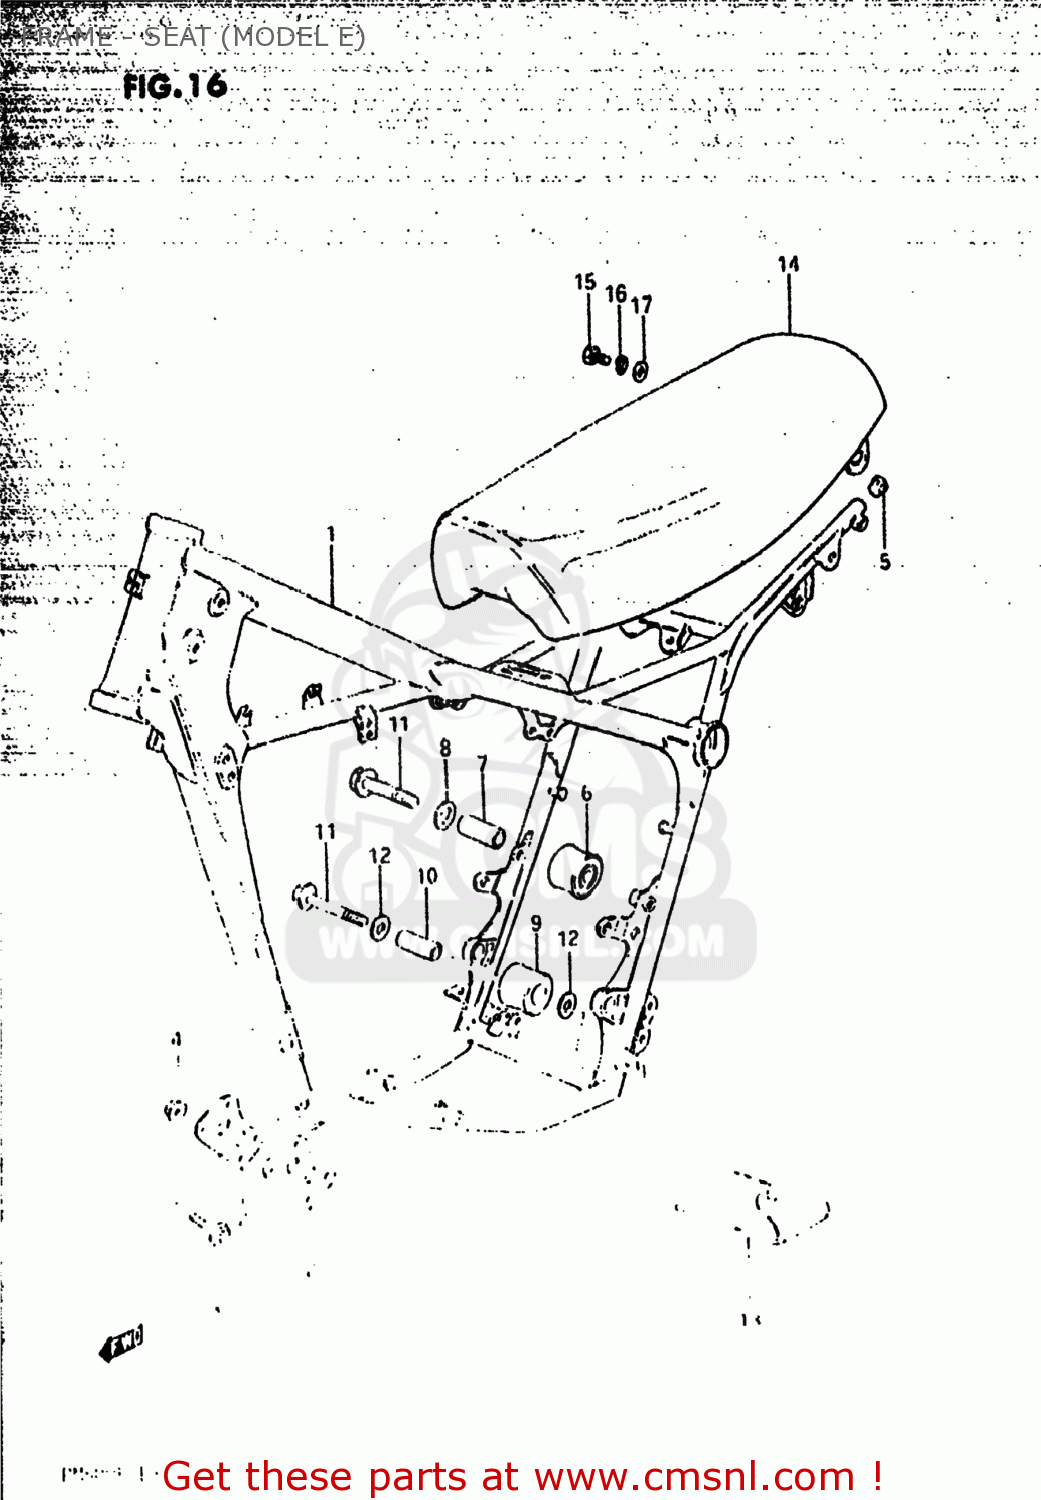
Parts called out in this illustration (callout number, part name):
1	FRAME
2	PLATE,ENGINE MOUNTING
3	BOLT(8X75)
4	NUT
5	PLUG(OD:17)
6	ROLLER,CHAIN
7	SPACER,CHAIN LENGTH ROLLER
8	WASHER
9	ROLLER,CHAIN LENGTH CONTROL
10	SPACER(8.6X12X25.5)
11	BOLT(8X45)
12	WASHER
13	TOOL SET
14	SEAT ASSEMBLY
15	BOLT
16	LOCK WASHER
17	WASHER
